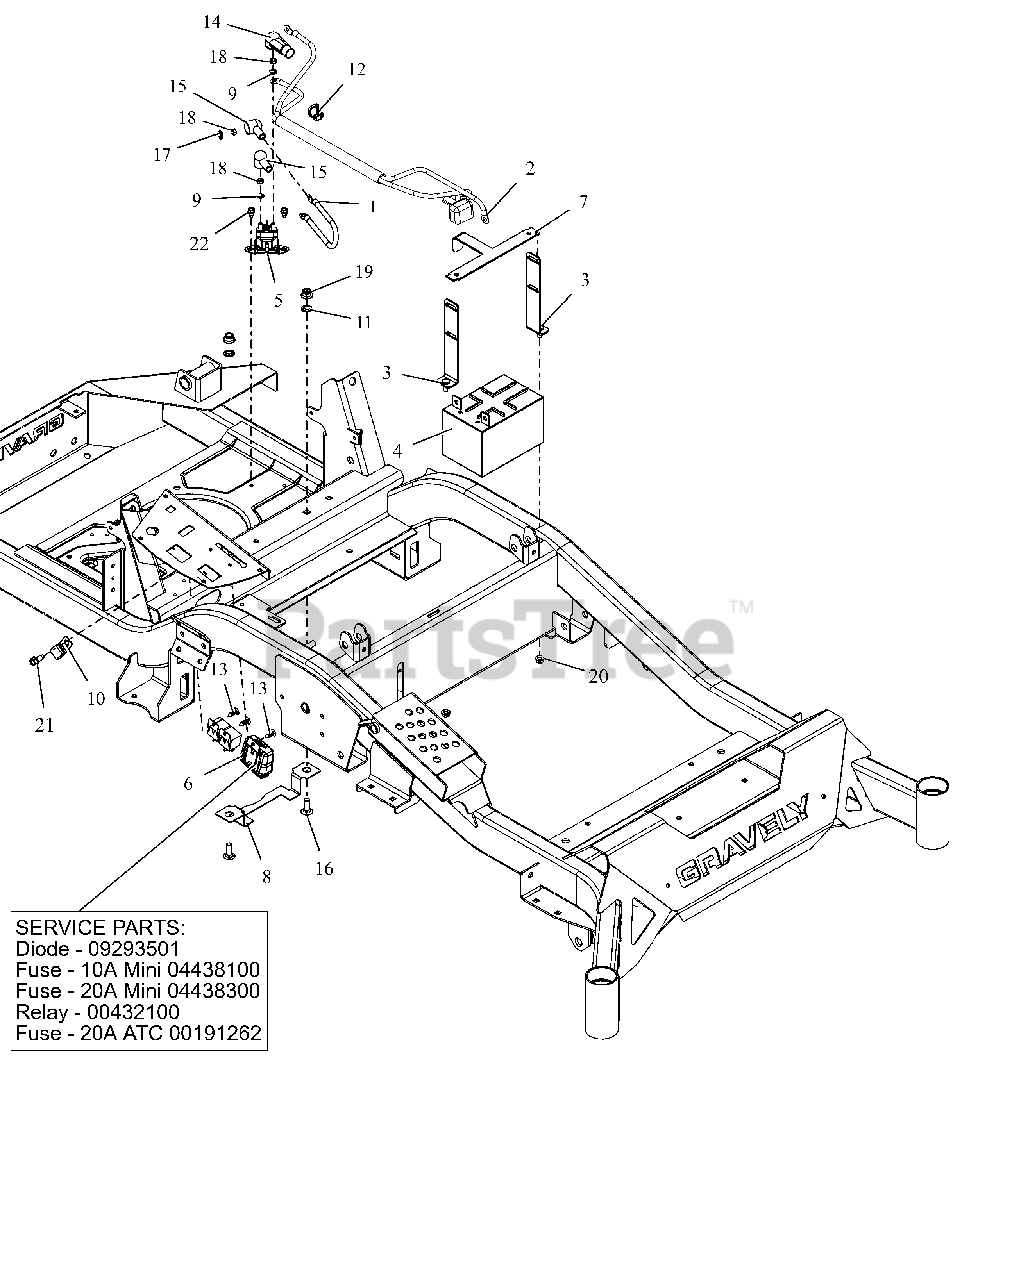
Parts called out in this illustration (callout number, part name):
1	CABLE, POS W/(2)1/4 RING 9.0LG
2	HARNESS, BATTERY HD
3	WMT,BATTERY MOUNT HOLD DOWN
4	BATTERY, 12V 12A-190CCA
5	SOLENOID, STARTER (SEALED)
6	HARNESS, WIRE
6	DIODE, CONNECTOR SHELL
6	FUSE,10 AMP MINI-ATC
6	FUSE,20 AMP MINI ATC
6	RELAY
6	FUSE, 20 AMP BLADE S/O
7	BRKT, BATTERY TIE DOWN
8	GUARD, ELECTRICAL HARNESS
9	@WSHR-LK-EXT.262X.502X.026YWZC
11	NUT-PUSH .38 DIA. PAL ZINC
12	CABLE TIE W/ TREE (.25 HOLE)
13	RIVET, .25 NYLON PANEL
14	BOOT, .65ID POS
15	BOOT, EYELET TERMINAL
16	@BLT-RDHDSQNK .38-16X1.00 G5YZ
17	@WSHR-LK .31X.078 REG YWZC
18	NUT-HEX M6X1.0 YWZC
19	@NUT-LK-NYL-FLG .38-16 YWZC
20	@NUT-LK-TOP-FLG .25-20 YWZC
21	@SCR-TAP .31-18X.75 HWH TR YWZ
22	@SCR-TAP .25-20X.37 HWH YWZ TR
